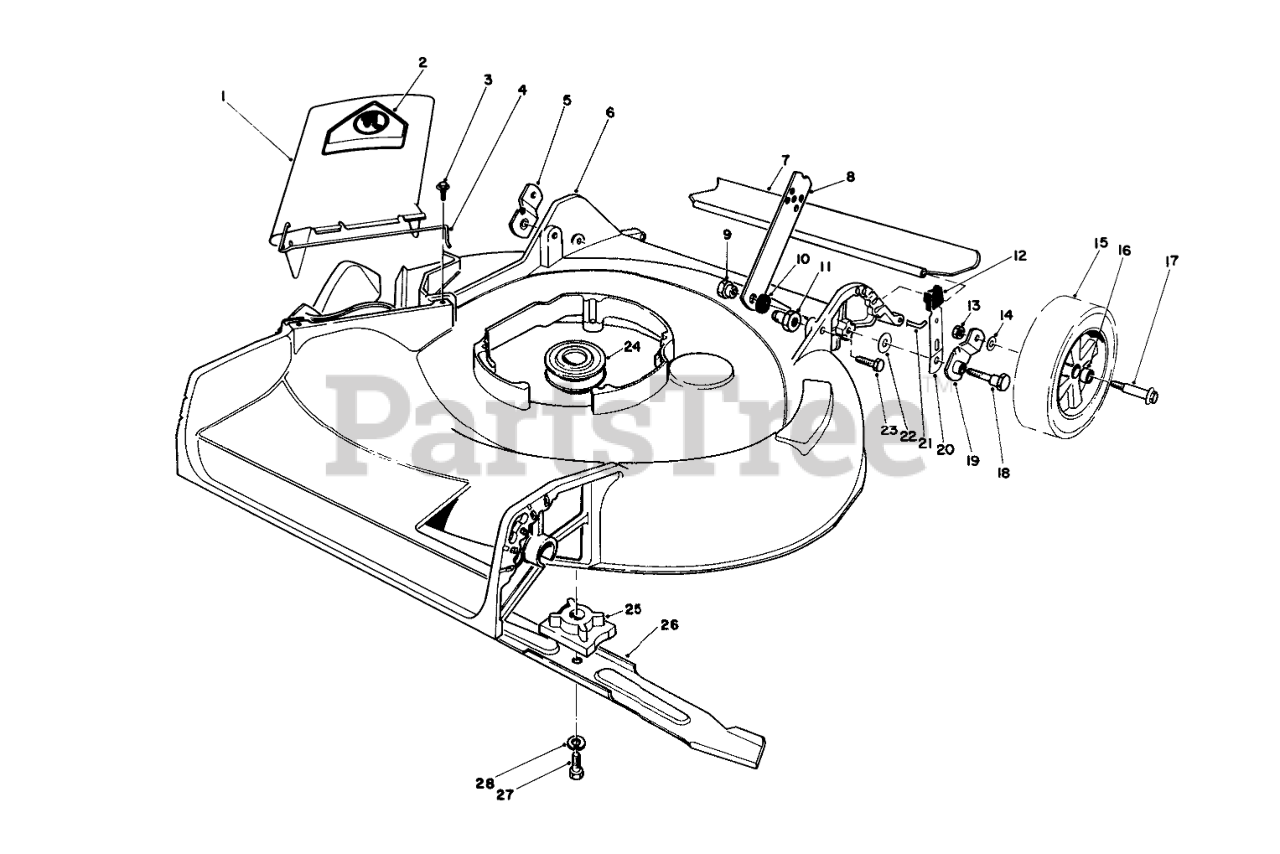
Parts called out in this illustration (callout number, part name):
1	Deflector (Incl. Ref. #2 & 4)
2	DECAL-DANGER
3	SCREW-HWH
4	SPRING HINGE
5	Pivot Arm
6	Housing
7	REAR SAFETY SHIELD 21
8	HANDLE LATCH
9	HANDLE PIVOT NUT
10	SPACER
11	HANDLE PIVOT NUT
12	KNOB-ARM
13	Nut
14	WASHER
15	Wheel & Tire Assembly (Incl. Ref. #16)
16	BUSHING
17	BOLT-WHEEL
18	PIVOT SCREW
19	Pivot Arm
20	SPRING ARM ASM
21	SHIELD ROD
22	WASHER-PIVOT
23	SCREW-HH
24	Pulley
25	BLADE RETAINER
26	Blade
27	SCREW-HH
28	WASHER-LOCK
